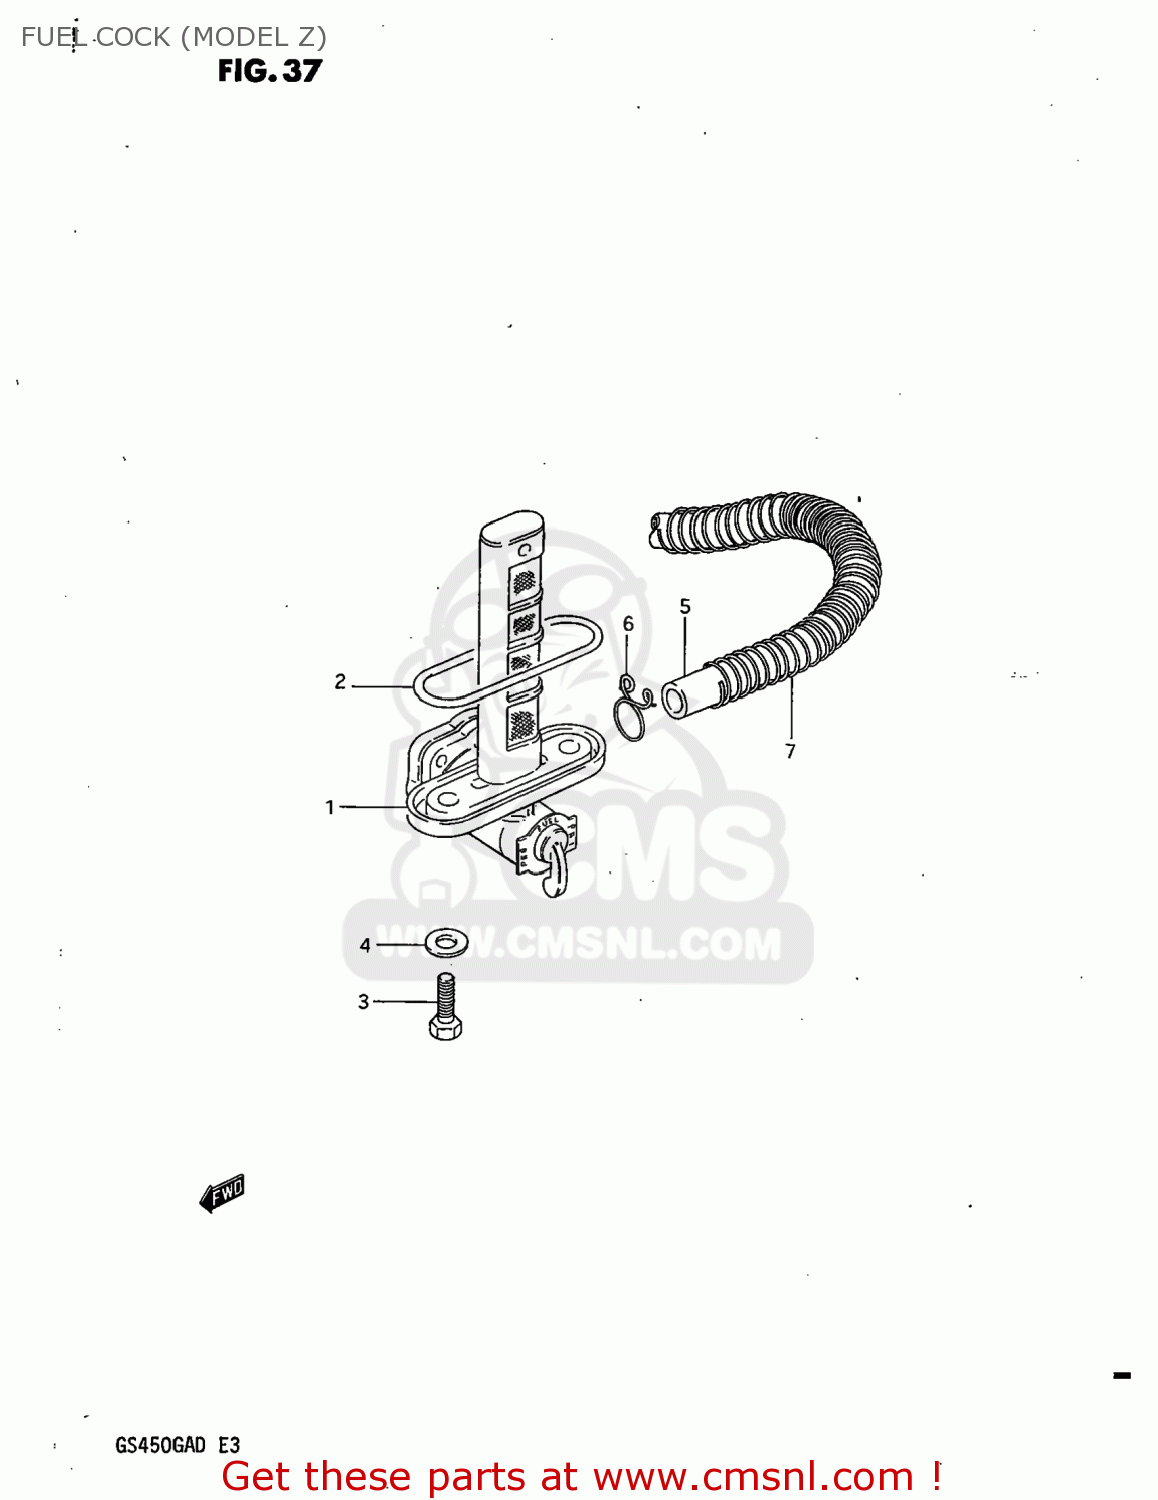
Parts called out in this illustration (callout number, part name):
1	COCK ASSEMBLY,FUEL
2	O RING
3	BOLT(6X20)
4	GASKET
5	HOSE
6	CLIP
7	SPRING
